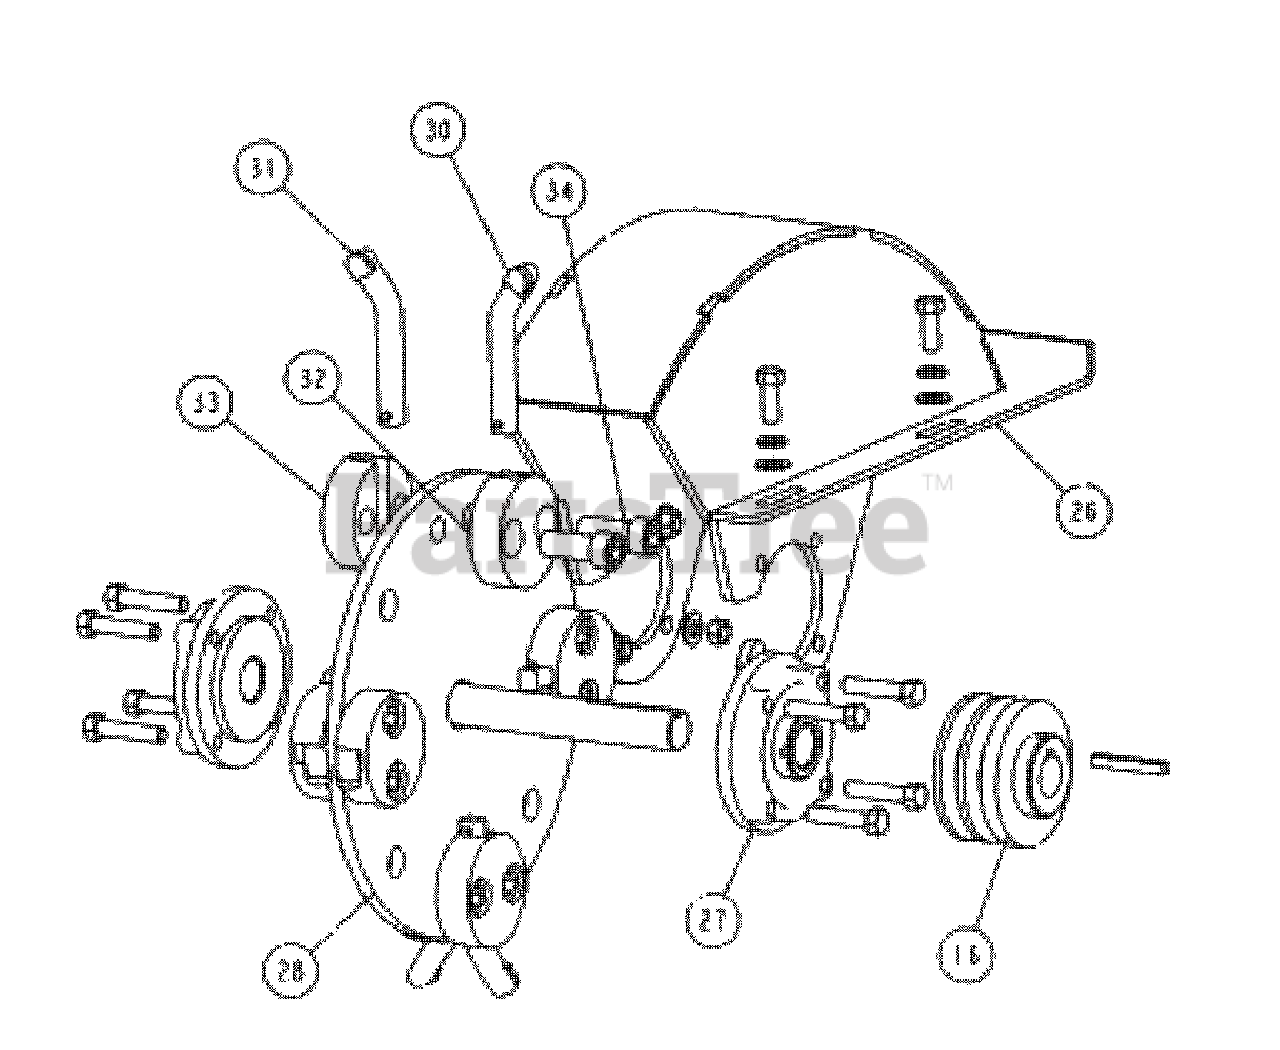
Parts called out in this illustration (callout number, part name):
16	Double V-Pulley
26	Cutting Wheel Shroud Kit
27	Bearings, Flange
28	Cutting Wheel Assembly
30	Right Tooth (1 ea)
31	Left Tooth (1 ea)
32	Counter Bore Pocket (1 ea)
33	Threaded Pocket (1 ea)
34	Socket Head Screw (2 ea)
